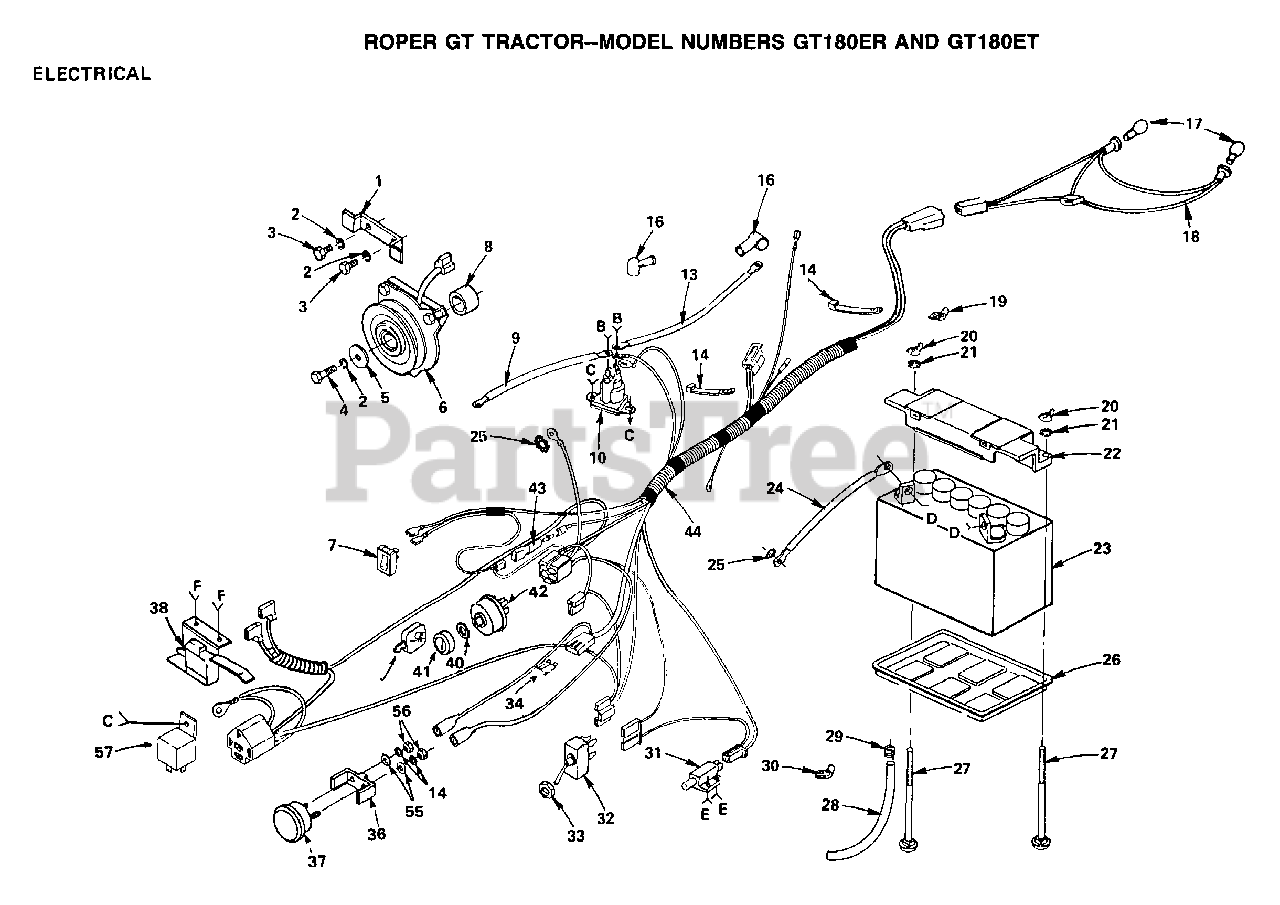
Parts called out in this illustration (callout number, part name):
1	STOP CLUTCH T
2	LOCKWASHER
3	BOLT
4	BOLT
5	WASHER GT
6	CLUTCH.ELECTRIC.T
7	SWITCH LT
8	SPACER-CLUTCH GT
9	CABLE-BATTERY T
18	HARNESS T
21	LOCKWASHER GT
24	CABLE T
26	"TRAY T, BATTERY"
27	BOLT
29	HOSE CLAMP T
30	CLIP GTV
31	SWITCH-INTER. GT
32	SWITCH.PTO.T
33	HEX NUT T
34	FUSE-30 AMP
37	AMMETER T
55	WASHER
57	RELAY ASSY T
